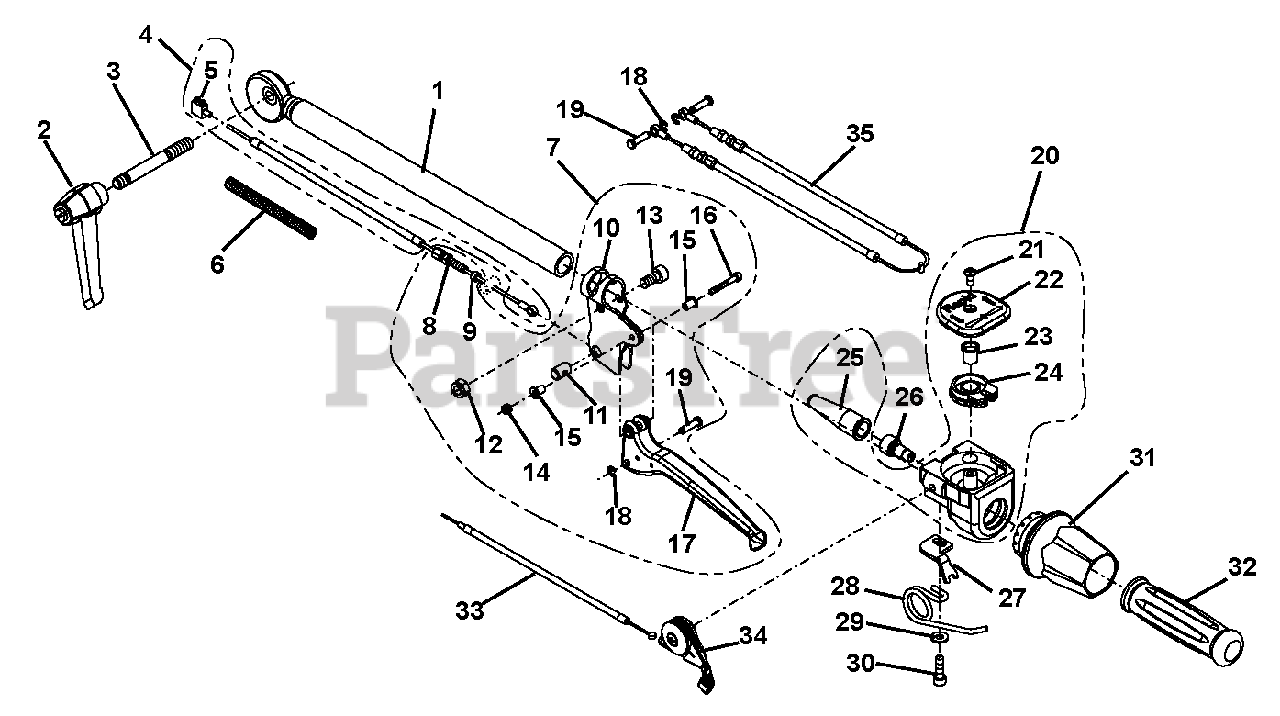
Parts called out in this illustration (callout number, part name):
1	Handlebar Extension
2	Clamping Lever, L= 80 M10 x 20
3	Threaded Bolt, D939 M10FO x 75
4	Cable Pull, INKL. (Includes item 5)
5	Nipple, 2 MM
6	Spring Tension
7	Lever, Assembly
8	Set Collar, M6 x 36
9	Distance Ring
10	Guide, Lever
11	Shaft, Stay
12	Nut, Lock, D985 Metric 8
13	Screw, D912 Metric 8 x 16
14	Nut, Lock, D985 Metric 4
16	Screw, D912 Metric 4 x 30
18	Washer, Lock
20	MF Control Unit CPL (Includes items 21 - 25)
21	Screw, ISO7380 M5 x 12/ 10.9
24	Bevel Wheel W. Cam
26	Nipple, Screwed
27	Cover, Stop
28	Spring, Return
29	Washer, M6
31	Bushing, Grip
32	Rubber, Handle
34	Assembly, Throttle Lever
35	Assembly, Cable
